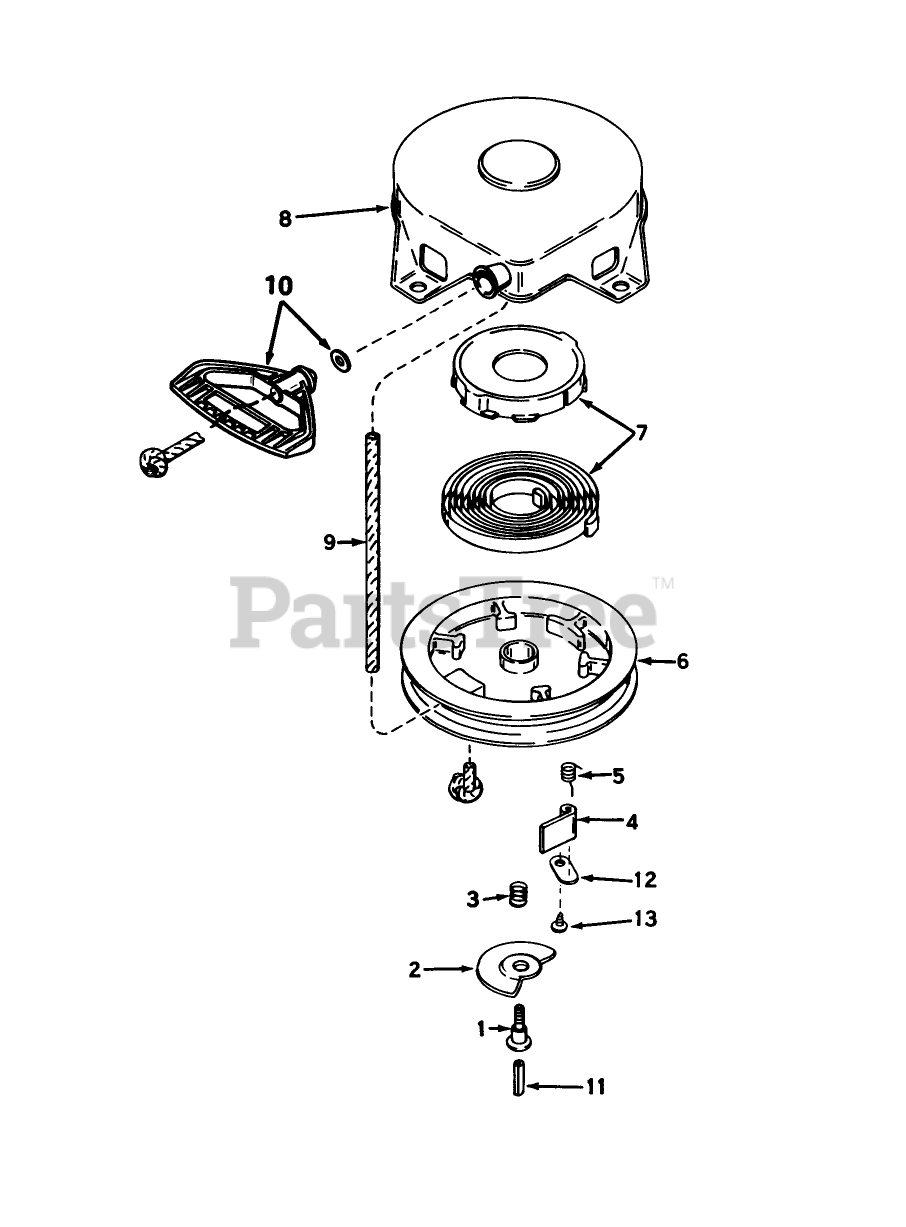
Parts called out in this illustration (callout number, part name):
1	Screw
2	Cam-Dog
3	Spring-Brake
4	Dog-Starter
5	Spring-Dog
6	Pulley
7	Spring Keeper Assy
8	Housing Assy.-Starter (Incl. Ref. #1)
9	Rope, Starter
10	Handle-Starter, Mitten Grip
11	Centering
12	Retainer-Dog
13	Screw
